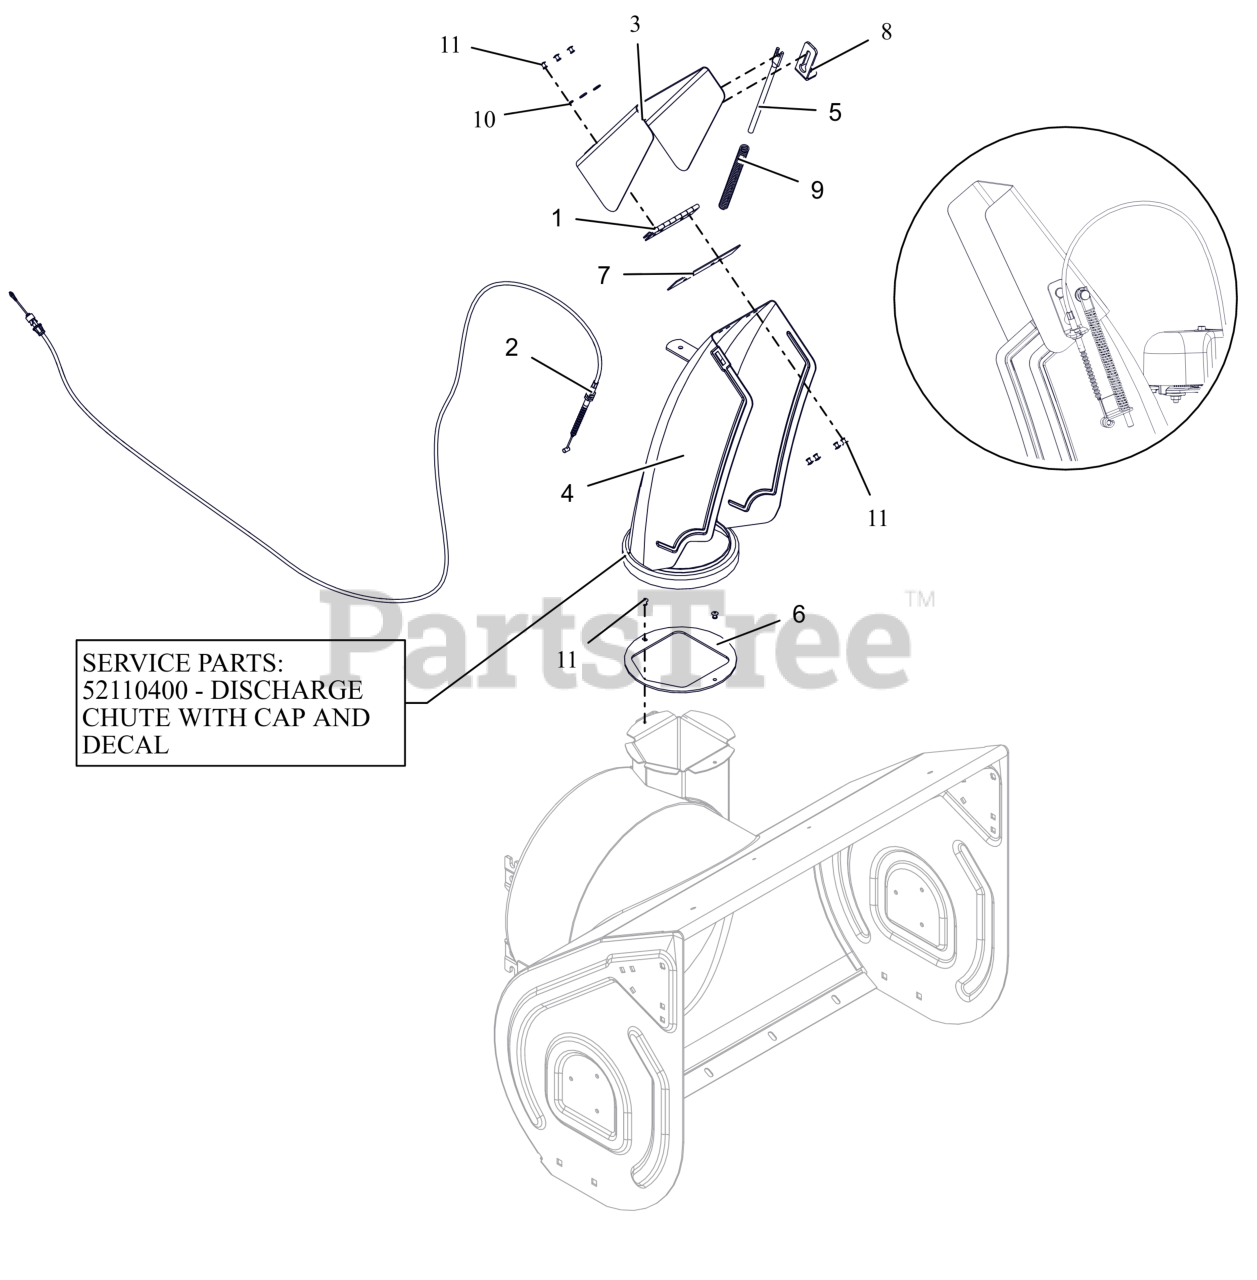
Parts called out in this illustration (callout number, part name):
2	CABLE, DEFLECTOR - DELUXE
3	CAP, LARGE REMOTE W/DECAL
4	CHUTE,DISCHARGE,NOTCHED,QT
4	CHUTE, DISCHARGE W/CAP
5	ROD, DEFLECTOR CAP
6	BAFFLE, DISCHARGE NECK
7	CAP SEAL 5.50
8	BRACKET, ANCHOR-CHUTE CABLE
9	SG-COMP .08X.40X6.50 14#/IN
10	WSHR,FLT .196X.500X.066 ZCC
11	RVT, POP .1875 ZCC
